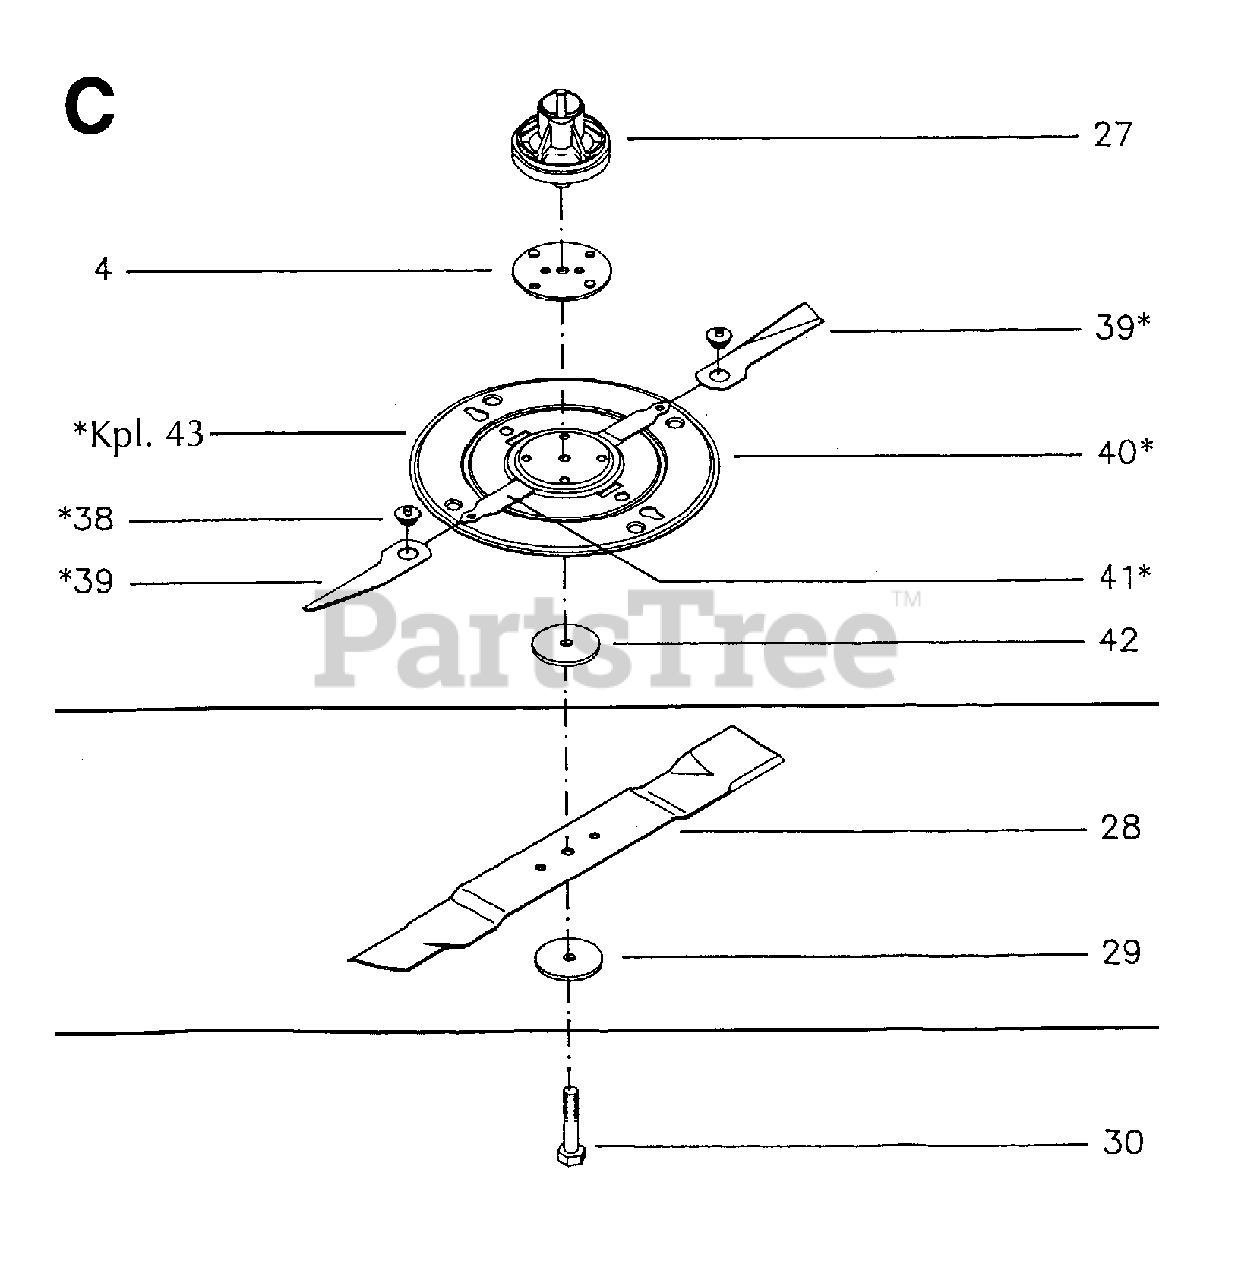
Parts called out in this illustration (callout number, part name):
4	STEEL PLATE ADAPTER
39	CUTTER BLADE
43	ROTORPLATE ASSY
